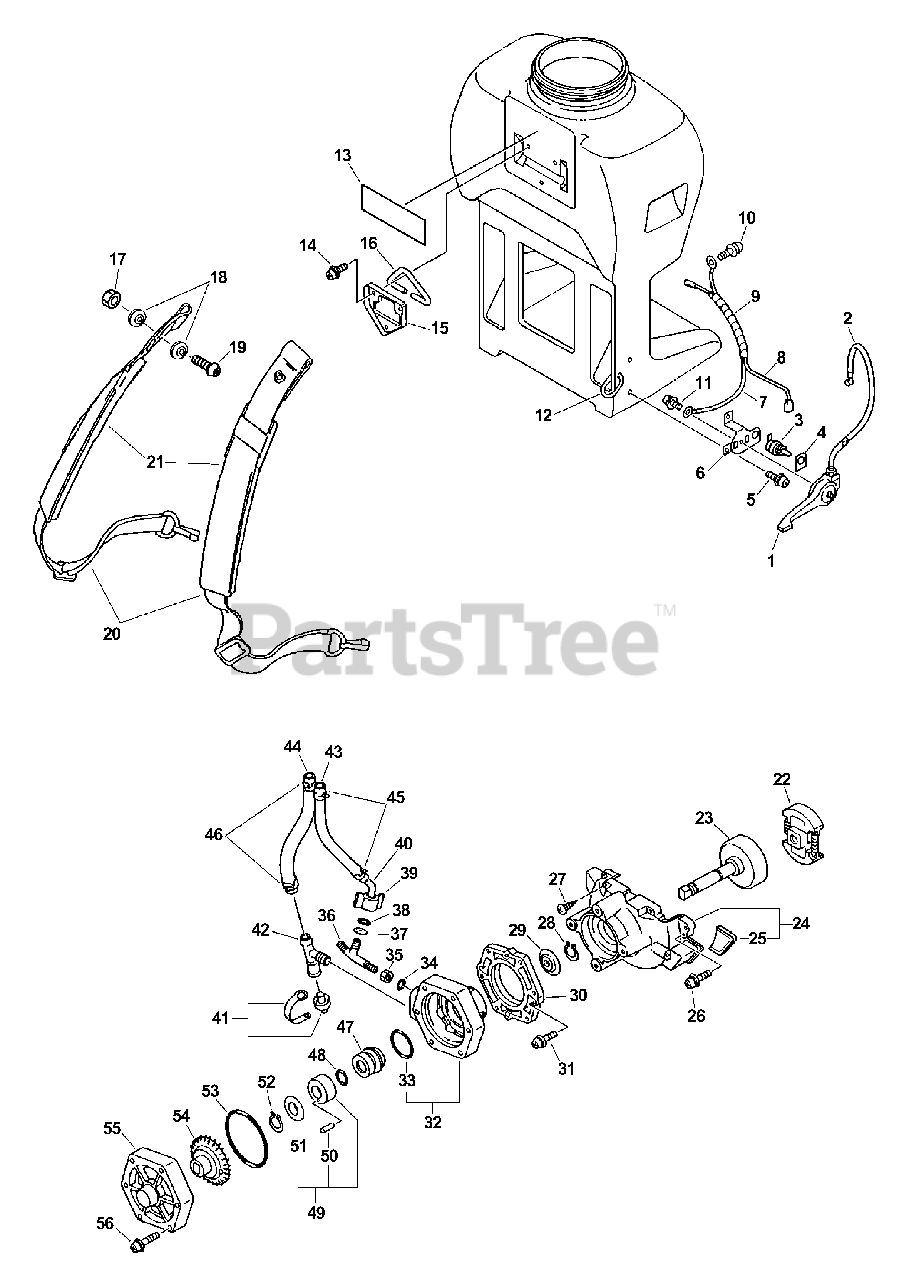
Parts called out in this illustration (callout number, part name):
1	LEVER, THROTTLE
2	CABLE, THROTTLE
3	IGNITION SWITCH ASSY
4	LABEL - SWITCH
5	SCREW - 5X16
6	BRACKET, THROTTLE
7	LEAD - GROUND
8	LEAD - GROUND
9	WRAP, SPIRAL
10	SCREW - 5X10
11	SCREW - 5X10
12	RING, STRAP
13	LABEL - CAUTION
14	SCREW - 6X10
15	BRACKET, HANGER
17	LOCKNUT - 5
19	SCREW - 5X14
20	STRAP, BACKPACK
21	PAD, STRAP
22	CLUTCH ASSY
23	DRUM, CLUTCH
24	FAN CASE KIT
25	COVER, FAN
26	SCREW - 4X16
27	SCREW - 4X14
28	RING, RETAINING - 12
29	PLATE, SEAL
30	BRACKET, PUMP
31	SCREW - 6X16
32	CASE, PUMP
33	O-RING - 29
34	O-RING - 10
36	NIPPLE, OUTLET PUMP
38	GASKET, BYPASS NOZZLE
39	WINGNUT
40	JOINT, BYPASS
41	DRAIN PLUG KIT
43	HOSE, FLUID
44	HOSE, FLUID
45	CLIP - 10
48	O-RING - 10
49	SEAL
52	RING, RETAINING - 12
53	O-RING - 67
54	IMPELLER
55	LID, PUMP
56	SCREW - 5X40
